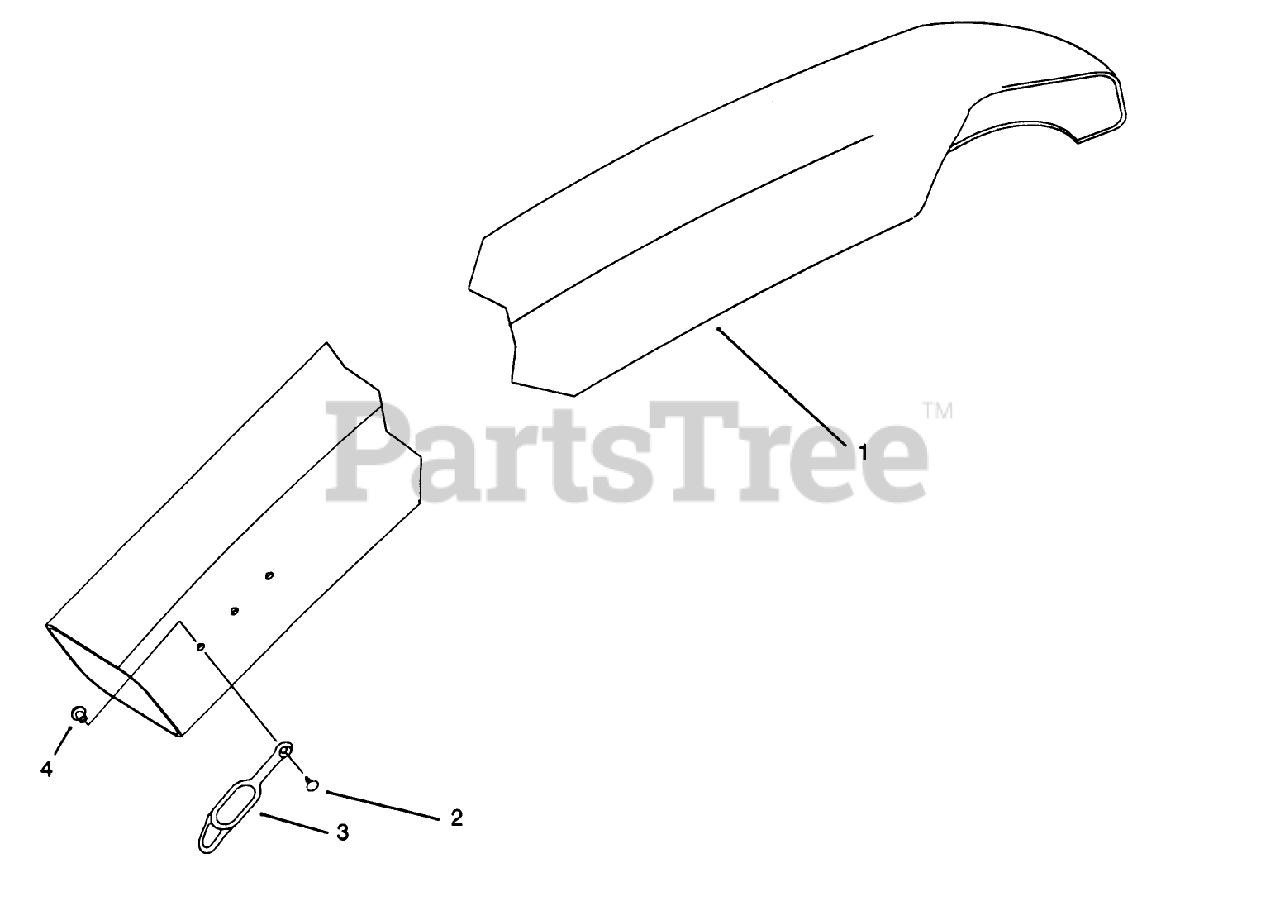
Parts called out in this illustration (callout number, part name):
1	CHUTE-DISCHARGE
2	FASTENER-PANEL
3	RETAINER-DUCT
4	SPACER-INTERLOCK
